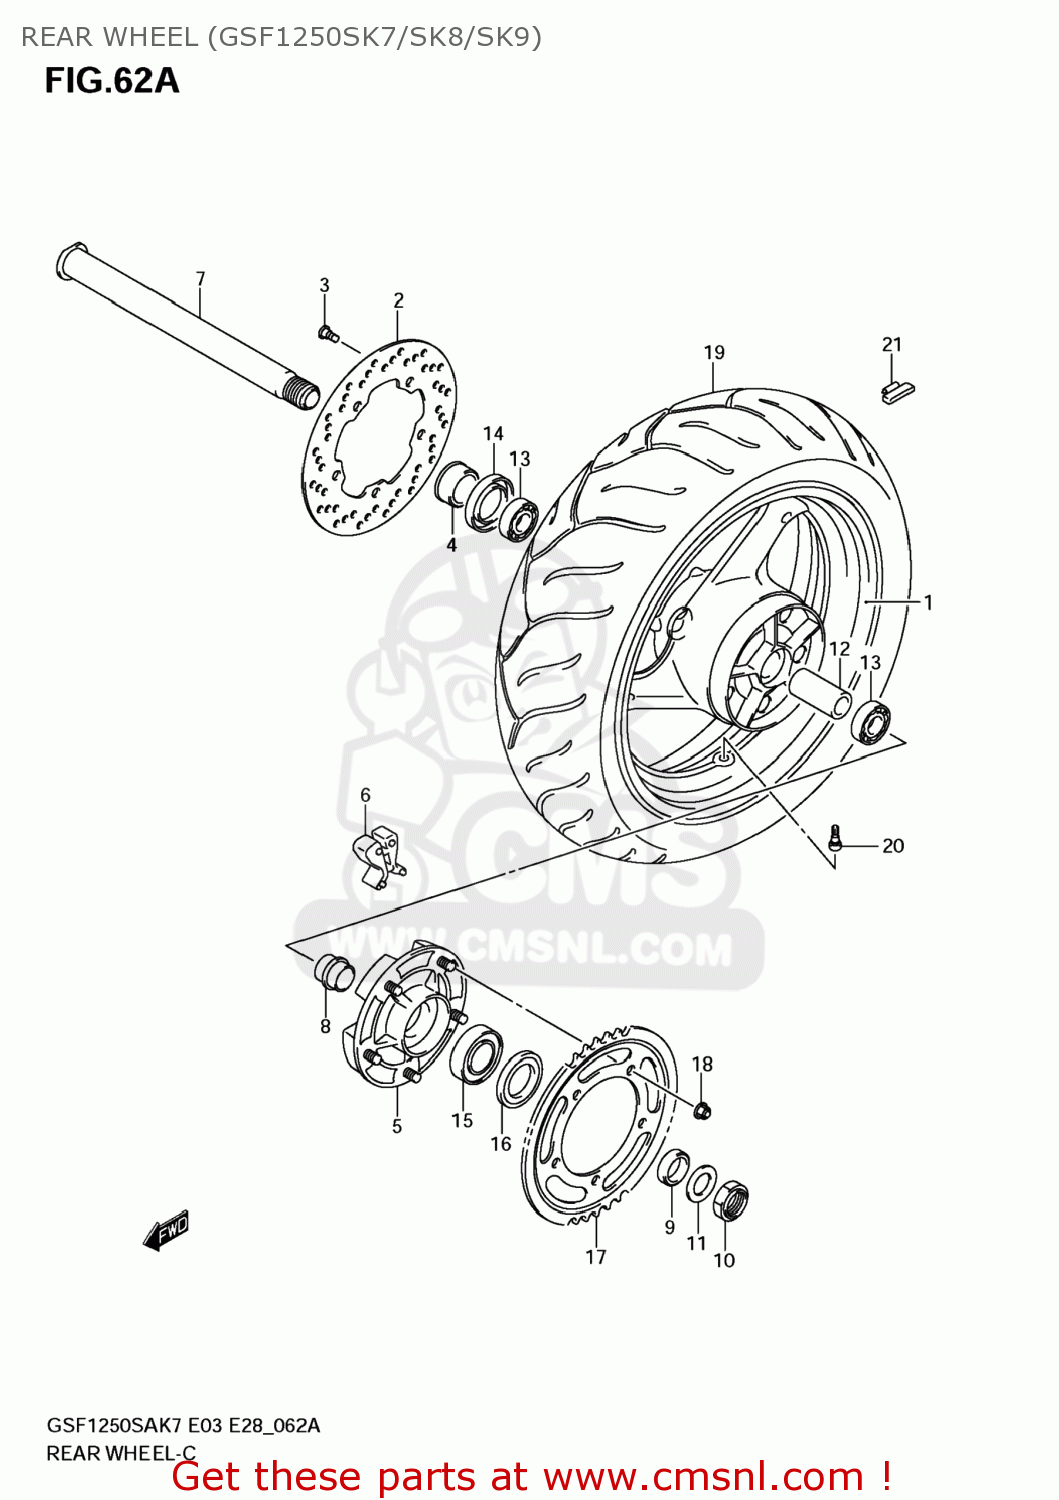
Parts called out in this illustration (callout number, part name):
1	WHEEL,RR(17M/CXMT5.50)
2	DISC,RR BRAKE
3	BOLT(8X21)
4	SPACER,RR AXLE,R
5	DRUM,RR SPROCKET
6	ABSORBER,RR HUB SHOCK
7	AXLE,RR
8	RETAINER,RR SPROCKET DRUM
9	SPACER,RR AXLE,L
10	NUT
11	WASHER(25.2X42X3.2)
12	SPACER,RR HUB BEARING
13	BEARING(28X52X12)
14	SEAL,OIL(37X52X8)
15	BEARING
16	SEAL,OIL(39X65X7)
17	SPROCKET,REAR(
18	NUT
19	TIRE,RR(180/55 ZR17M/C 73W)
20	VALVE ASSY,WHEEL RIM(TR412)
21	BALANCER,WHEEL(10G)
